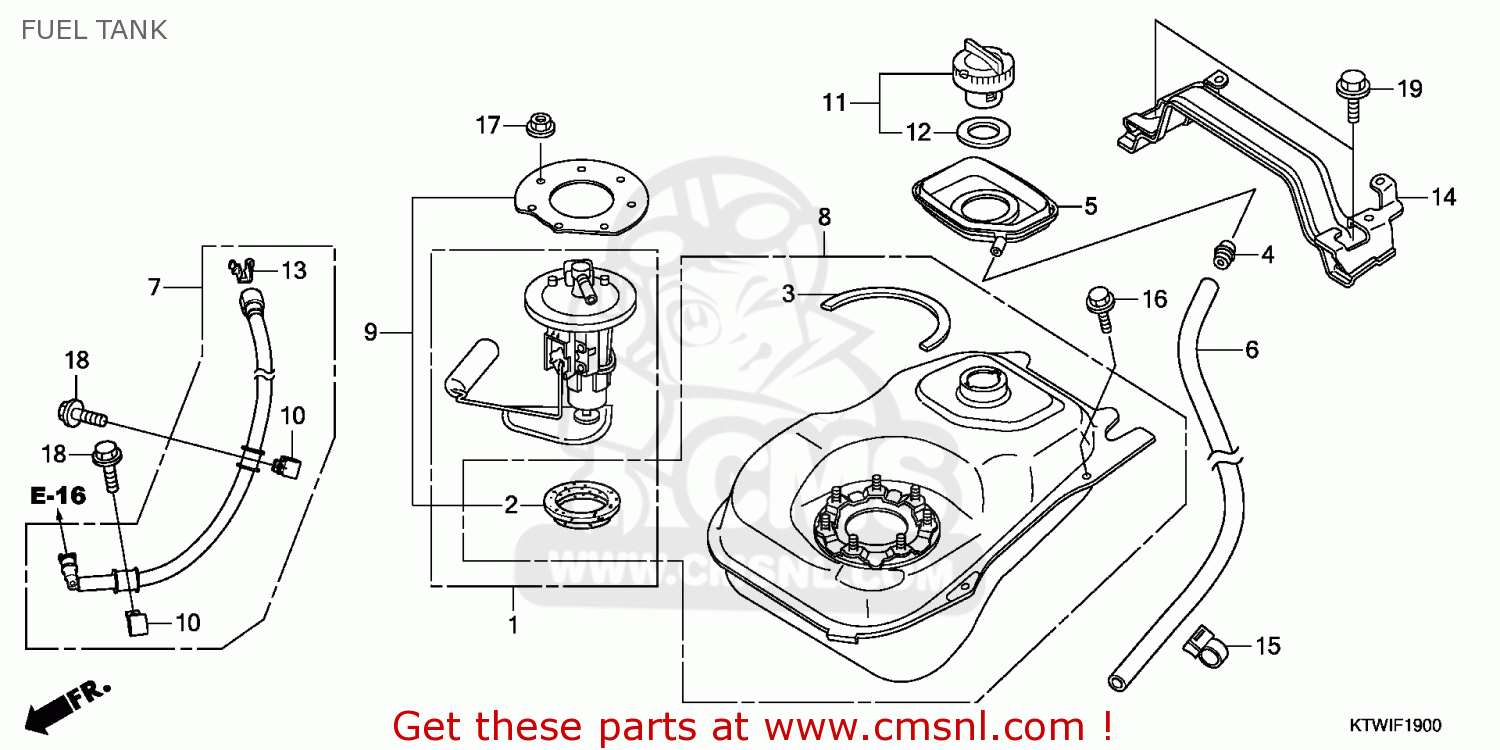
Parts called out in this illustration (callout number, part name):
1	UNIT SET,FUEL PUM
2	PACKING A,FUEL PU
3	SEAL,FUEL TANK
4	JOINT,FUEL TUBE
5	TRAY,FUEL
6	TUBE,DRAIN
7	HOSE COMP,FUEL FE
8	TANK SET,FUEL
9	PLATE SET,FUEL PU
10	CLAMPER,FUEL HOSE
11	CAP COMP,FUEL FIL
12	PACKING,FUEL FILL
13	RETAINER
14	BRKT,RR CROSS
15	CLIP,CABLE 12MM
16	BOLT-WASHER,6X12
19	BOLT FLANGE 8X16
